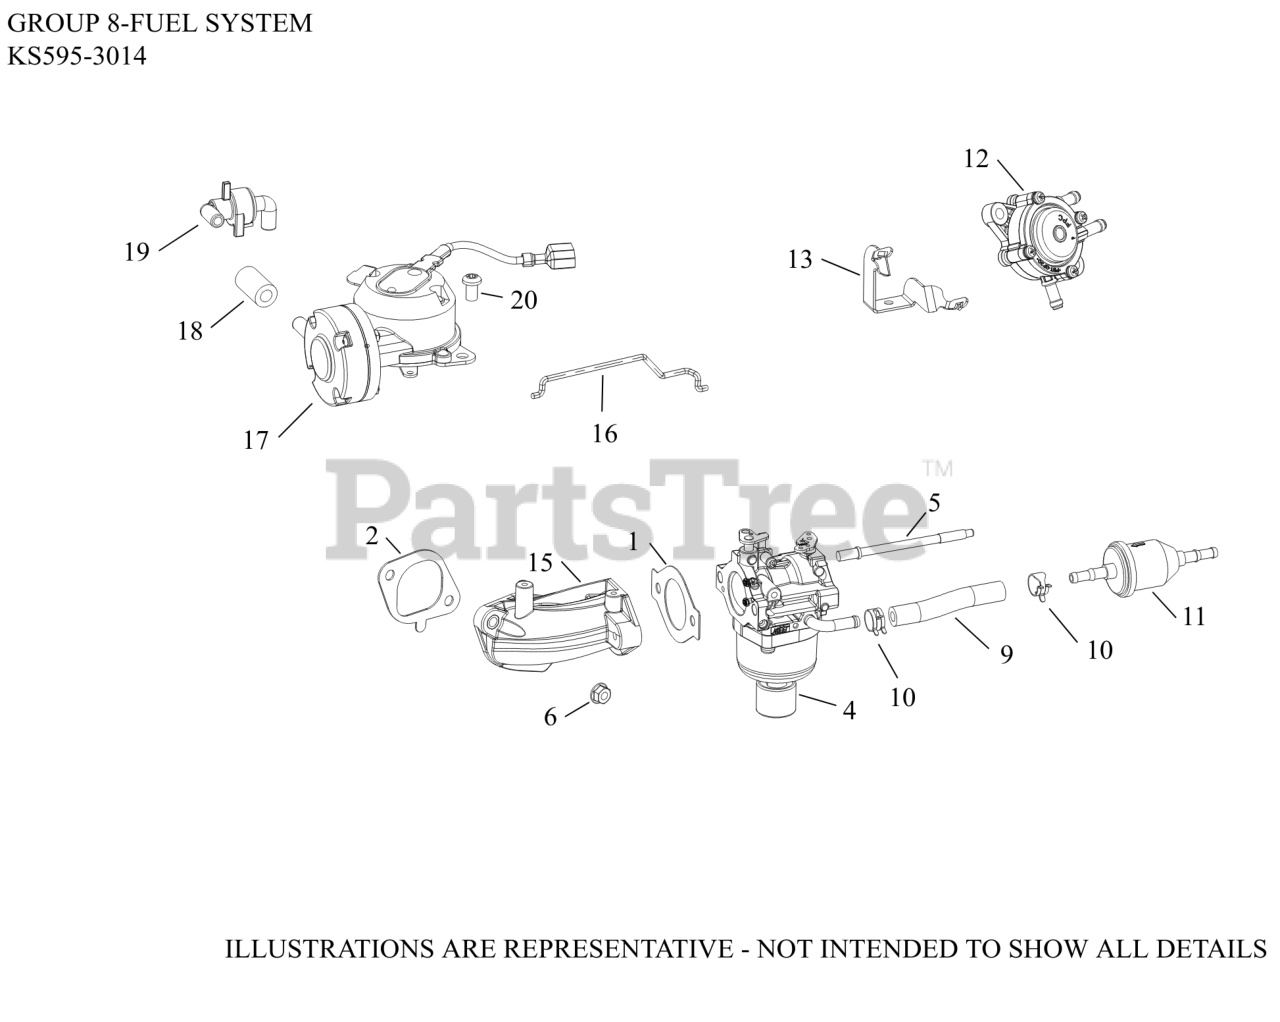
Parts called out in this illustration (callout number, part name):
1	GASKET, CARBURETOR (THROTTLE)
2	GASKET, INTAKE MANIFOLD
4	KIT,CARB(NIKKI)
5	STUD, CARBURETOR
6	NUT, FLG M6X1.0
9	HOSE,LW PERM.FUEL 24.00"-USE 25 111 81-S
10	SPRING CLAMP, HOSE
11	FILTER,FUEL 51 MICRON (FUEL PUMP)
12	PUMP, FUEL (PULSE)-(#2539326S)
13	BRACKET, FUEL PUMP
15	MANIFOLD, INTAKE ASSY
16	LINKAGE, CHOKE
17	DIAPHRAGM ASSY
18	HOSE, VACUUM
19	CHECK VALVE ASSY
20	SCREW, K40 X 1.79 TFS
NI	HIGH ALTITUDE KIT (5000 FT)
NI	KIT, OVERHAUL
NI	KIT, CHOKE SHAFT
NI	KIT, O-RING
NI	KIT, SOLENOID (NIKKI)
NI	KIT, BOWL WITH O-RINGS
NI	KIT, FLOAT & INLET NEEDLE FOR FUEL PUMP
NI	KIT, THROTTLE SHAFT
